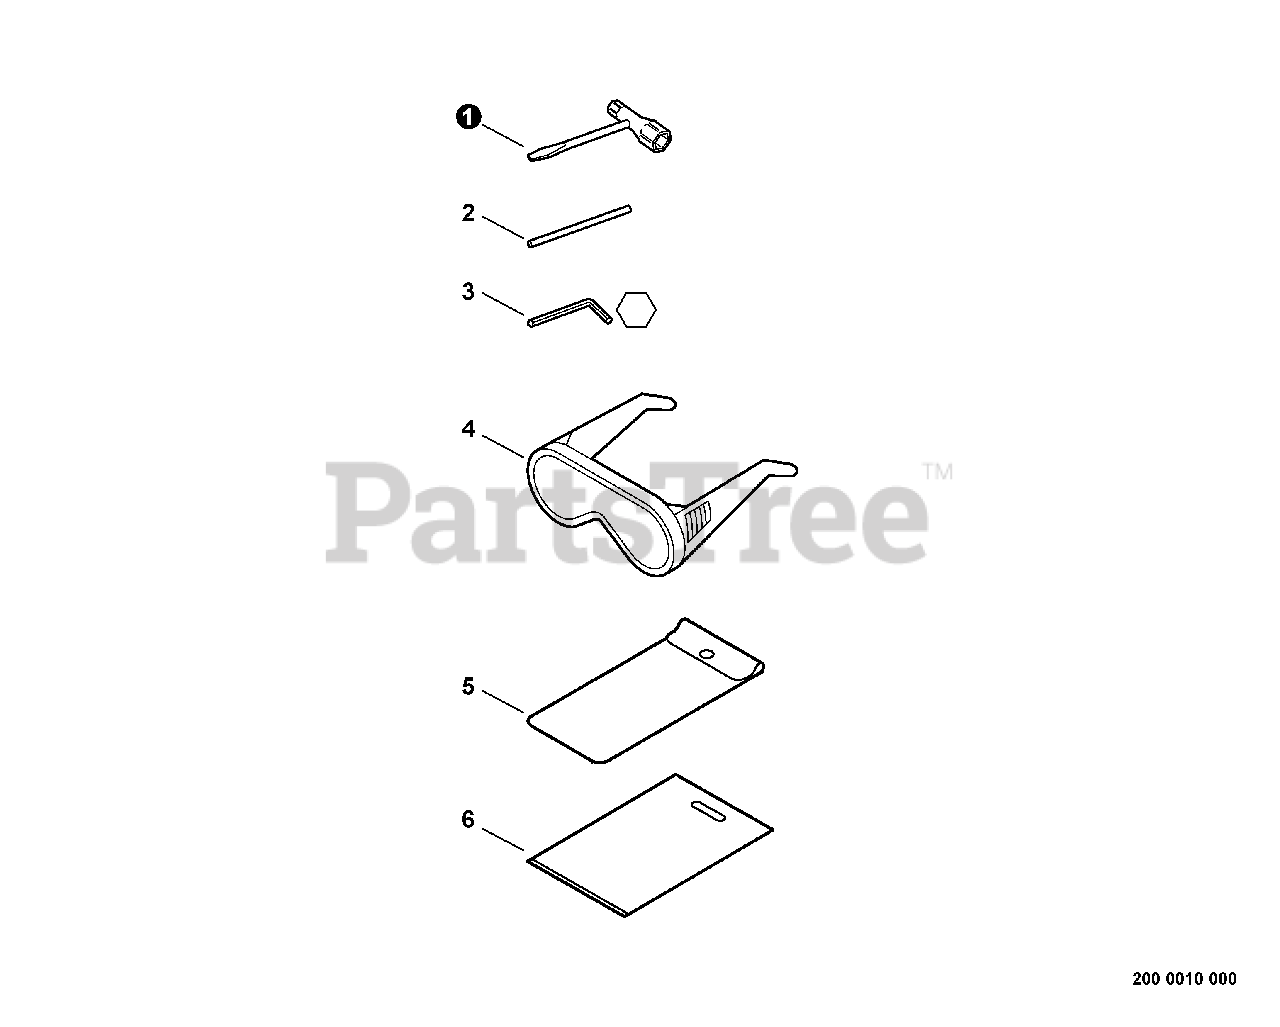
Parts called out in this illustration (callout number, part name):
1	T-WRENCH 17x-19 L200
2	TOOL, LOCKING 5×120 MM
3	WRENCH, ALLEN 4 MM
4	GLASSES, SAFETY
5	BAG, TOOL
6	CASE, TOOL
